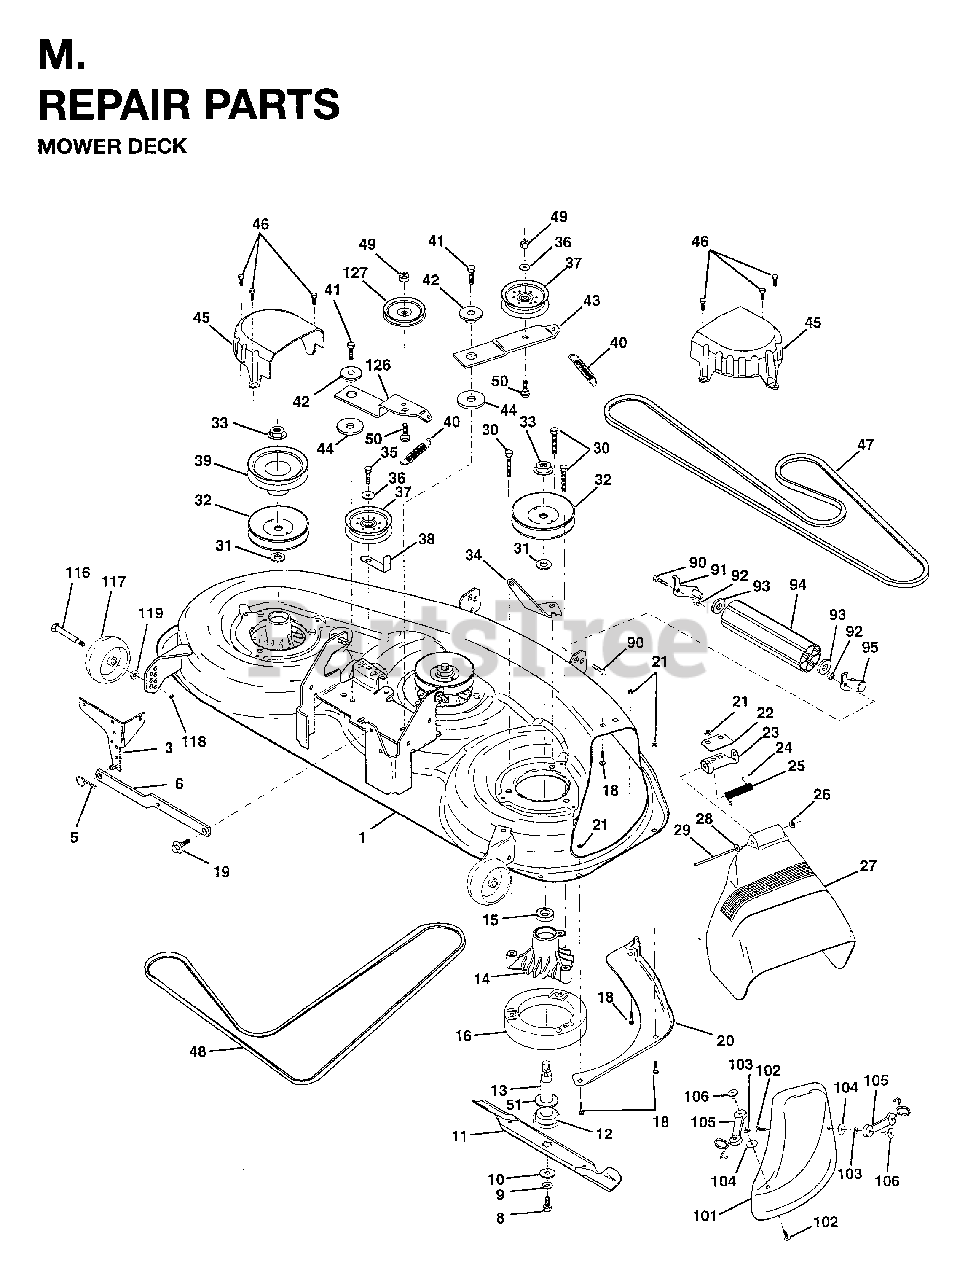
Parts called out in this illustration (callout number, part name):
1	DECK ASM, MOWER 46"
3	BRACKET SWAY BAR
5	RETAINER SPRING
6	REAR SUSP ARM
8	BLADE BOLT
9	WASHER, LOCK 3/8
10	WASHER.BLADE
11	BLADE 46"
12	BEARING
13	SHAFT.ASM.W/BEARING
14	HOUSING.MANDREL
16	STRIPPER
18	BOLT
19	BOLT SHD 5/16-18
20	BAFFLE, VORTEX MOWER 46"
21	LOCKNUT
22	STIFFENER BRACKET
23	DEFLECTOR BRACKET
24	CAP-SLEEVE LT
25	TORSION SPRING
26	NUT PUSH M
27	SHIELD, DEFLECTOR MOWER
28	WASHER - 15X7.3X1.6
29	ROD.HINGE
30	SCREW
31	WASHER
32	PULLEY
33	NUT
34	ANCHOR, SPRING DECK 46"
35	SCREW LT
36	WASHER
37	FLAT IDLER PULLEY
38	KEEPER
39	PULLEY.DRIVEN.DECK.46"
40	SPRING.SEC.44"VEN
41	BOLT
42	SPACER RETAINER
43	ARM IDLER DECK 46"
44	HARDENED WASHER
45	COVER MANDREL 46
46	SCREW.1/4-20X5/8
47	BELT V SECONDARY
48	V-BELT PRIMARY 50"
49	LOCKNUT
50	BOLT.3/8-14X1.25
91	BRACKET LH (A)
92	LOCKNUT
94	NOSE ROLLER
95	BRACKET RH (B)
118	LOCKNUT
119	WASHER
